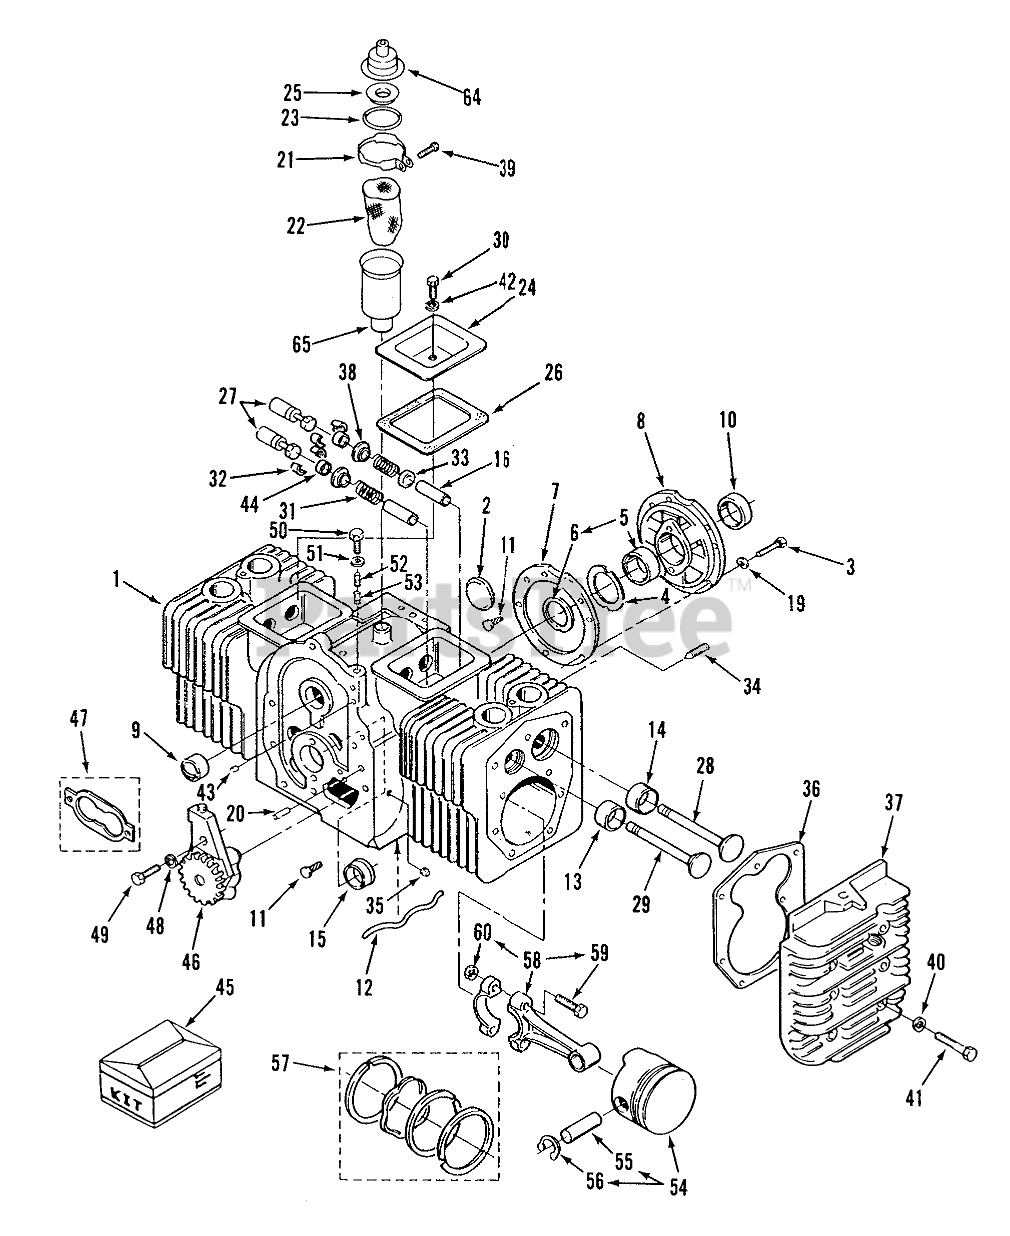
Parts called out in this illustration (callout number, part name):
1	Short Block
2	Plug
3	Bolt 3/8-16x 1-1/4
4	Shim 0.005"
5	Rear Crankshaft Bearing-STD
6	ThrustWasher
7	Gasket
8	Bearing Plate
9	Camshaft Brg
10	Oil Seal
11	Screw
12	Oil Tube
13	Standard
14	Standard
15	Standard
16	Exhaust Valve Guide
19	Lockwasher 3/8
20	Pin
21	Clamp
22	Baffle
23	Seal
24	VALVE-COVER L.H.
25	Screen
26	Gasket
27	Tappet
28	Intake Valve
29	Exhaust Valve
30	HHCS 1/4-20 X 1 3/4
31	Spring
32	VALVE SPRING LOCK
33	Seal
34	Screw
35	Plug
36	Gasket
37	Right Side
38	Washer
39	Screw #8 x 3/4
40	Washer
41	Special Bolt 2.375" Long
42	Washer
44	Cap-Valve
45	Engine Gasket Kit
46	Oil Pump
47	Oil Pump Gasket Kit
48	Washer-Lock
49	Bolt
50	Bolt
51	Washer
52	Spring
53	Piunger
54	Piston Pin & Retaining Rings-STD
55	Pin-Piston
56	Retaining Ring
57	Standard
58	Rod w/Bolts & Nuts-STD
59	Rod Bolt
60	Nut
64	Breather Cap & Valve
65	Breather Tube
